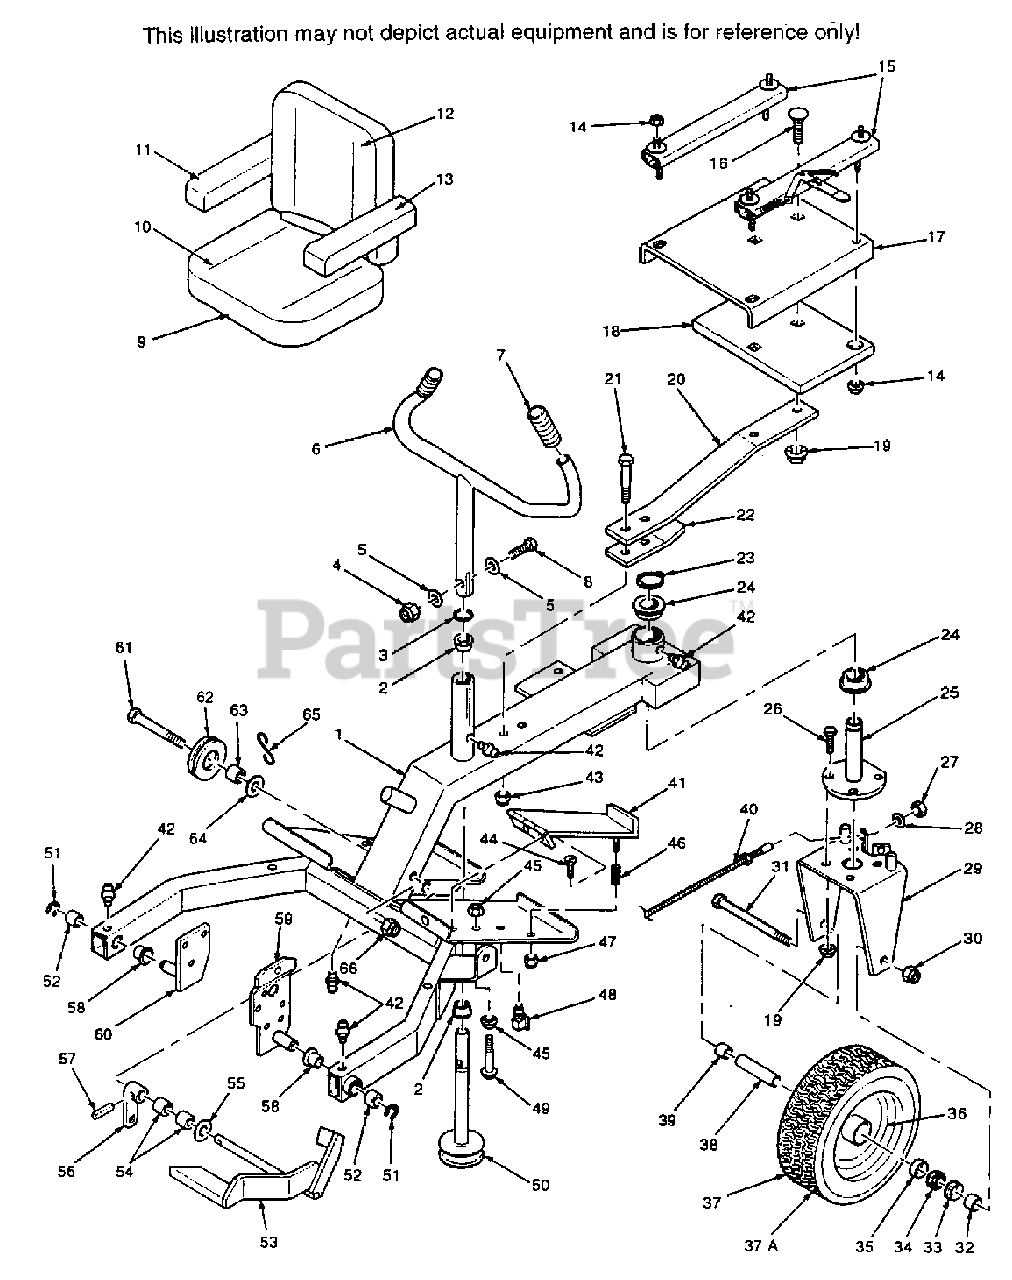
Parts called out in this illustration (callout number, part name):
1	STEERING FRAME(INCLUDES BUSHINGS AND
2	BRONZE BUSHING
3	RETAINING RING. 7/8 EXTERNAL
5	FLAT WASHER, 3/8 X 7/8 X 13 GA.
6	STEERING HANDLE(INCLUDES ITEM 7)
7	GRIP
9	SEAT ASSY.(INCLUDES ITEMS 10 THRU 15)
10	CUSHION ASSEMBLY
11	ARM PAD - R.H.
12	SEAT BACK CUSION
13	ARM PAD L.H.
14	SERR. FL. HH. NUT, 5/16-18
15	SEAT ADJUSTER TRACK
17	SEAT PLATE
18	BALLAST, SEAT MOUNT(72" CUTTER DECK ONLY)
19	SERR FL. HEX NUT, 3/8-16
20	SEAT SPRING
22	REINFORCEMENT, SEAT SPRING
23	RETAINING RING, 1-1/8" EXTERNAL
24	BRONZE BUSHING
25	REAR WHEEL PIVOT
28	LOCK WASHER, 3/8 INTERNAL TOOTH
30	HEX ELASTIC STOP NUT, 5/8-11
31	BOLT, HEX HD. 5/8-11 X 9"
32	SPACER, REAR WHEEL, SHORT
33	SEAL, GREASE
34	BEARING CONE
35	BEARING CUP
36	RIM ONLY
37	REAR WHEEL ASSY.(INCL. ITEMS 33-36, 37A)
37A	TIRE ONLY
38	SLEEVE, REAR WHEEL
39	SPACER, REAR WHEEL
40	CABLE, STEERING(INCLUDES HARDWARE)
41	PEDAL, FOOT SAFETY SWITCH
42	GREASE FITTING
45	SERR. FL. HEX NUT, 1/4-20
46	SPRING, FOOT SAFETY SWITCH
47	HEX NUT, ELASTIC STOP LOCK, 1/4-20
48	SWITCH, FOOT SAFETY
50	STEERING SHAFT
51	RETAINING RING 3/4 EXT. "E"
52	BRONZE BUSHING
53	FOOT PEDAL
54	BRONZE BUSHING
55	FLAT WASHER, 3/4 X 1-1/4 X 16 GA.
56	FOOT PEDAL ARM
57	PIN, DRIVE LOCK 3/16 X 1-1/4"
58	BRONZE BUSHING
59	SULKY MTG. BRKT. L.H.
62	PULLEY, WINCH CABLE
63	BRONZE BUSHING
65	RETAINER, WINCH CABLE
